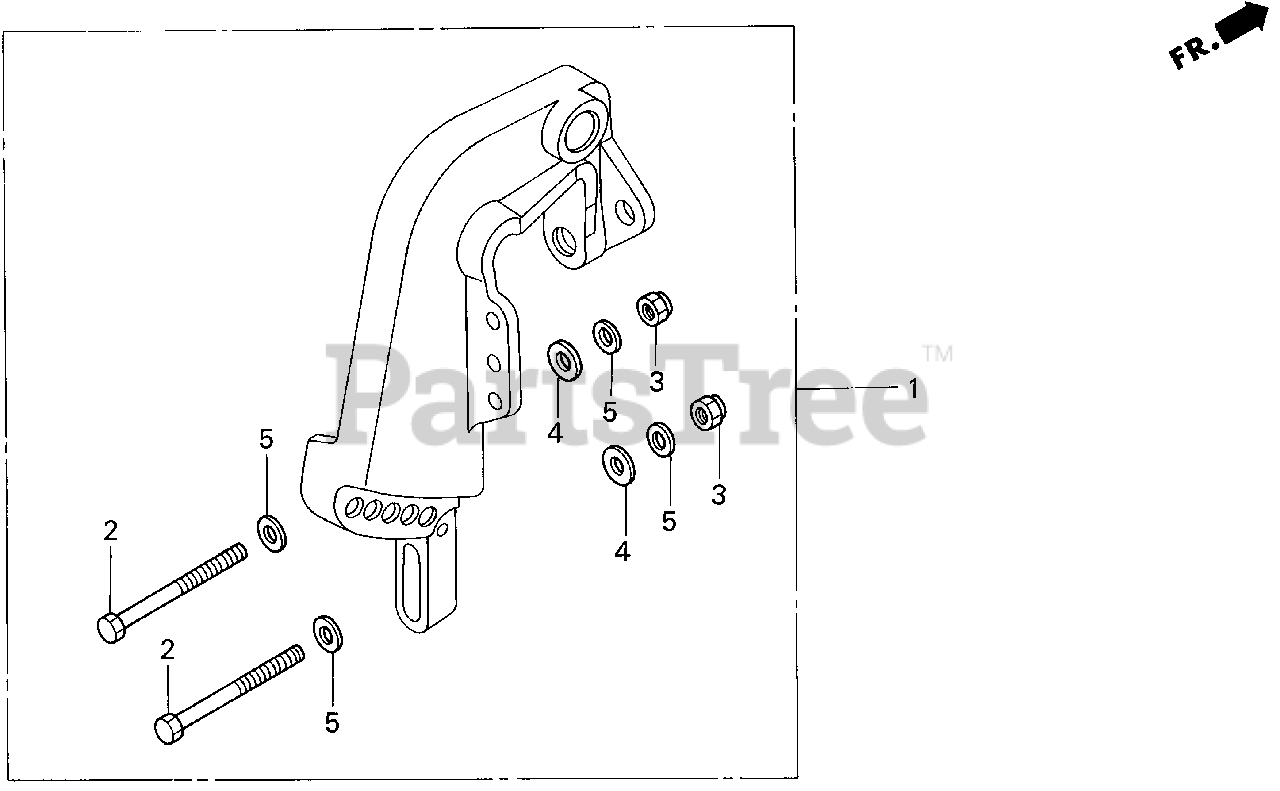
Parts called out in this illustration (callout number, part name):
1	INSTALLATION KIT
2	BOLT, HEX. (10X100)
3	NUT, SELF-LOCK (10MM)
4	WASHER, PLAIN (10MM)
5	WASHER, PLAIN (10MM)
